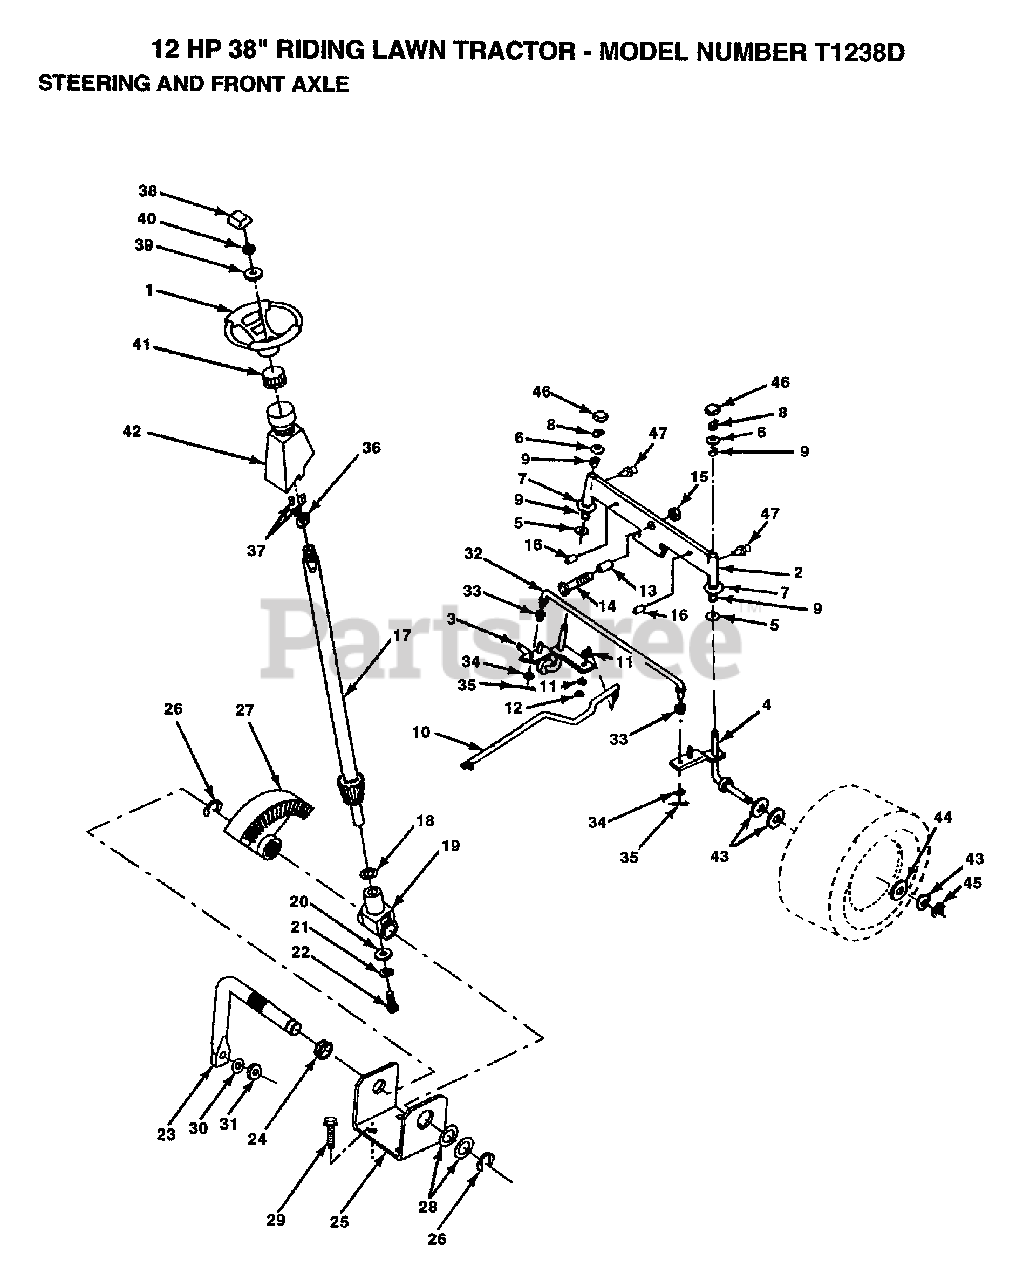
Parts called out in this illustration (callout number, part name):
3	SPINDLE LH
4	SPINDLE RH
5	WASHER .T
6	WASHER
7	WASHER
8	RING
9	COL. SRTG. BEAR.
11	LOCKWASHER
13	BEARING
14	BOLT HEX 5/8-11
16	AXLE PIN
17	SHAFT ASM
18	THRUST WASHER
19	SUPPORT.SHAFT
21	LOCKWASHER
22	"SCREW,SPECIAL"
24	NYLINER T
25	"BRKT,STEERING"
26	RING
28	WASHER .T
29	SCREW
30	LOCKWASHER
32	TIE ROD
33	BUSHING.DRAGLINK
34	WASHER
35	COTTER PIN
38	ST WHL INSERT CAP
39	WASHER T
40	GRIPCO NUT
41	ADAPTER-WHEEL LT
42	"TUBE, STR SHAFT"
43	WASHER
44	WASHER
45	RING
46	CAP
